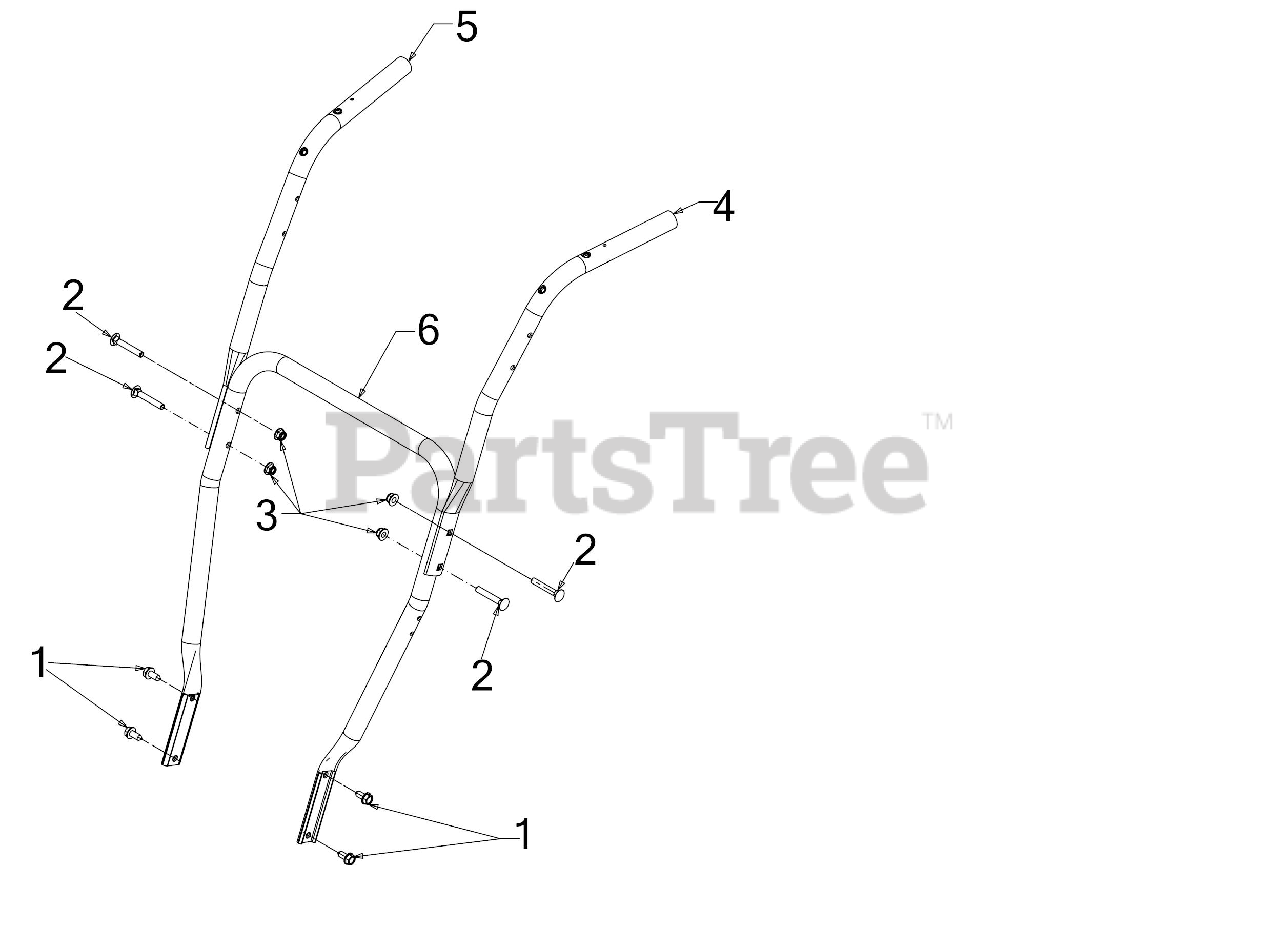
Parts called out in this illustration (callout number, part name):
1	SCREW 5/16-18 x .750
2	CARRIAGE BOLT 5/16-18 x 2.00 GR5
3	FLANGE LOCK NUT 5/16-18
